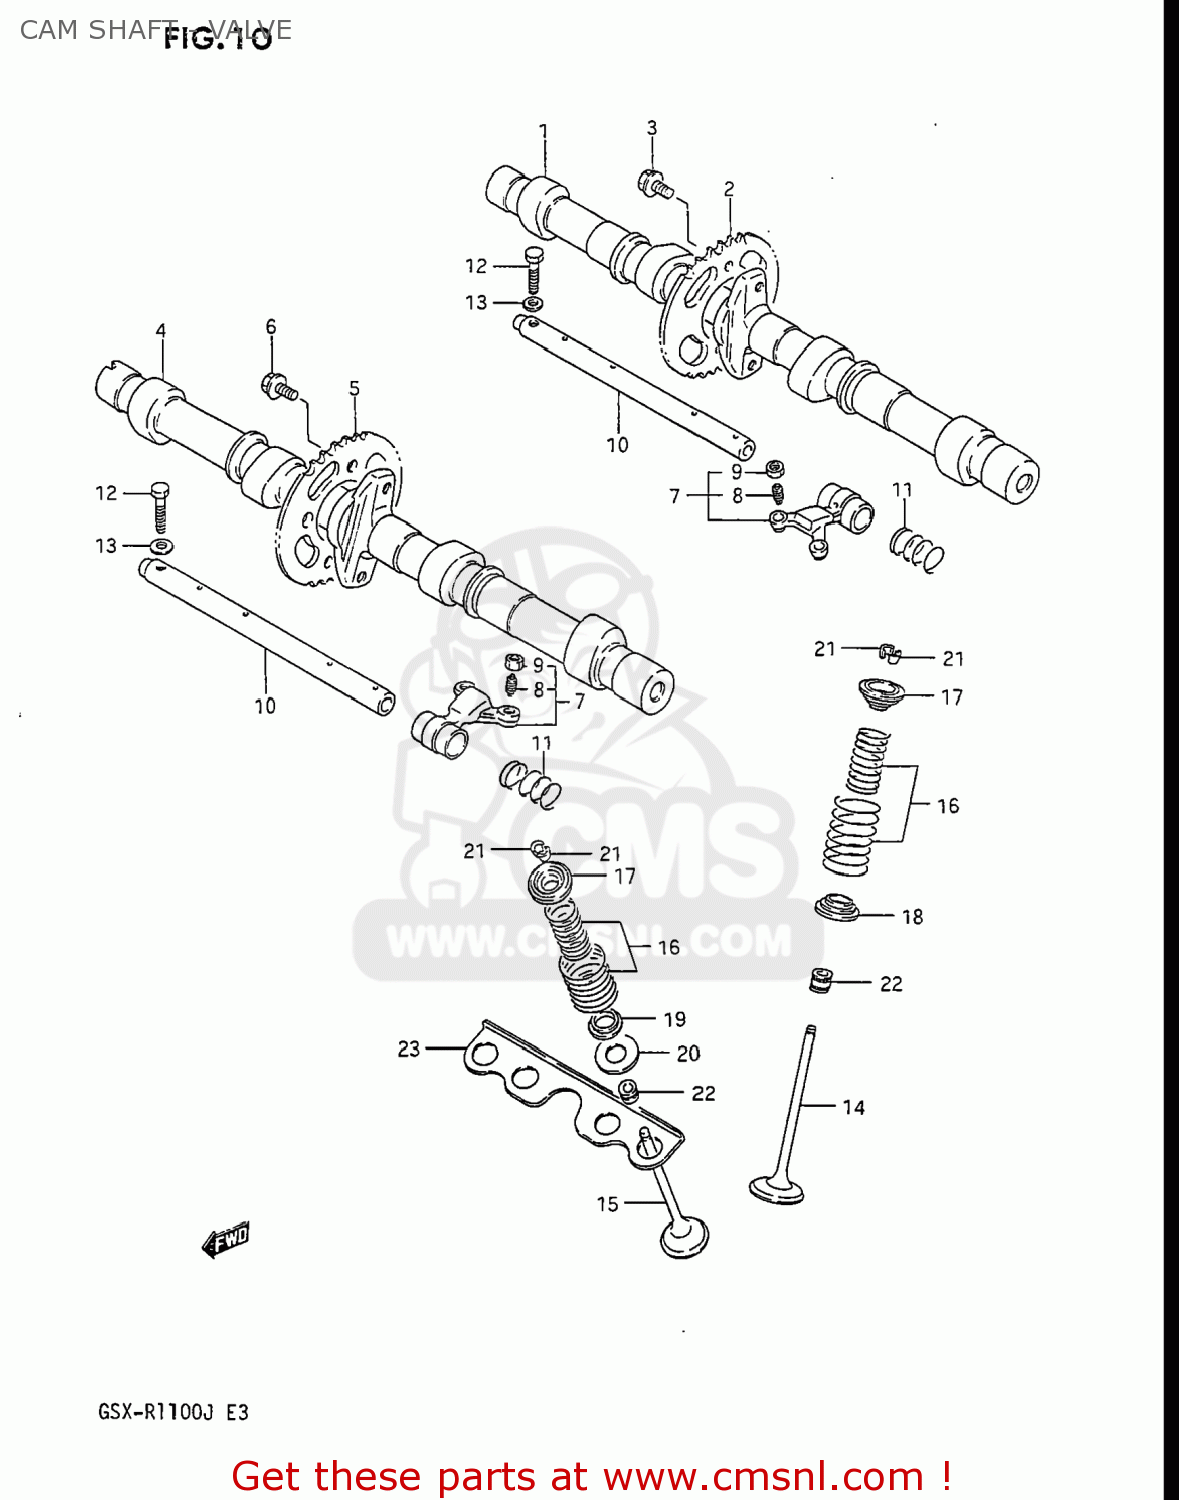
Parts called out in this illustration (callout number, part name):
1	CAMSHAFT
2	SPROCKET,CAMSHAFT
3	BOLT(7X11)
4	CAMSHAFT,EXHAUST
5	SPROCKET,CAMSHAFT
6	BOLT(7X11)
7	ARM,VALVE ROCKER
8	SCREW,TAPPET ADJUSTING
9	NUT,ADJUSTING
10	SHAFT,VALVE ROCKER ARM
11	SPRING
12	BOLT
13	WASHER, LOWER
14	VALVE,INTAKE
15	VALVE,EXHAUST
16	SPRING SET,VALVE
17	RETAINER,VALVE SPRING
18	SEAT,VALVE SPRING
19	SEAT,VALVE SPRING
20	SEAT,VALVE SPRING EXH OUTER
21	COTTER VALVE
22	SEAL,OIL(5X10X9.7)
23	PLATE
